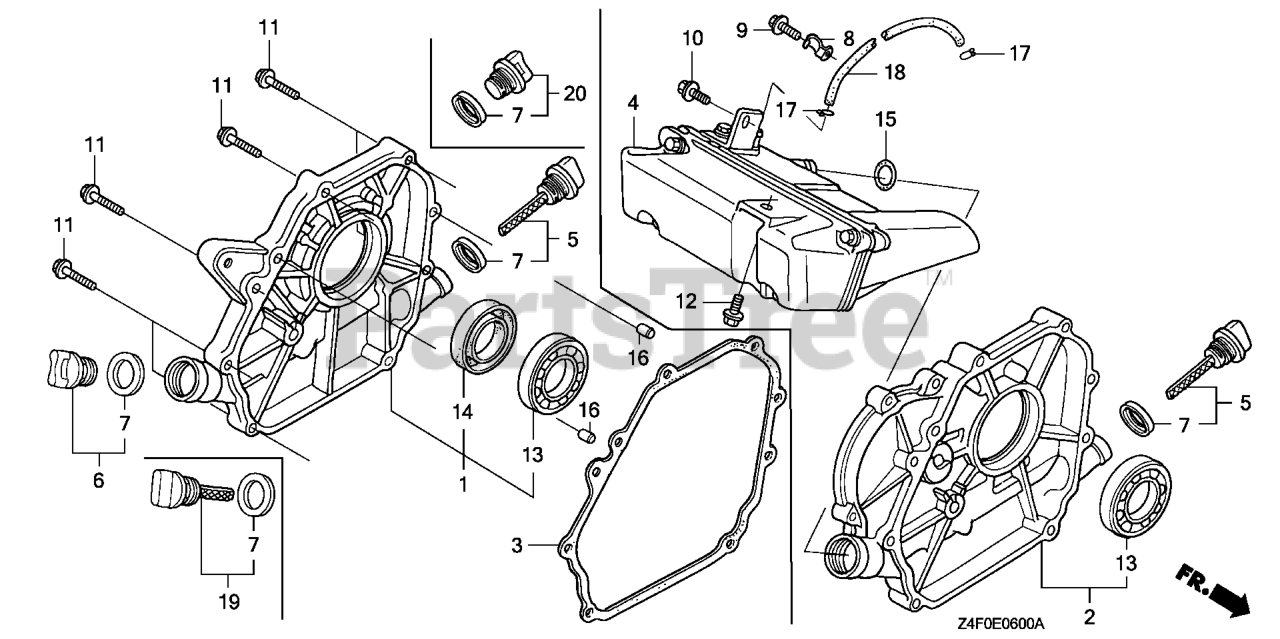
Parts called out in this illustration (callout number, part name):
1	COVER ASSY., CRANKCASE
3	GASKET, CASE COVER
5	CAP ASSY., OIL FILLER
6	CAP ASSY., OIL FILLER
7	GASKET, OIL FILLER CAP
11	BOLT, FLANGE (6X28) (CT200) Use up to Engine SN 1530314.
13	BEARING, RADIAL BALL (62/22)
14	OIL SEAL (22X41X6)
16	PIN A, DOWEL (8X14)
